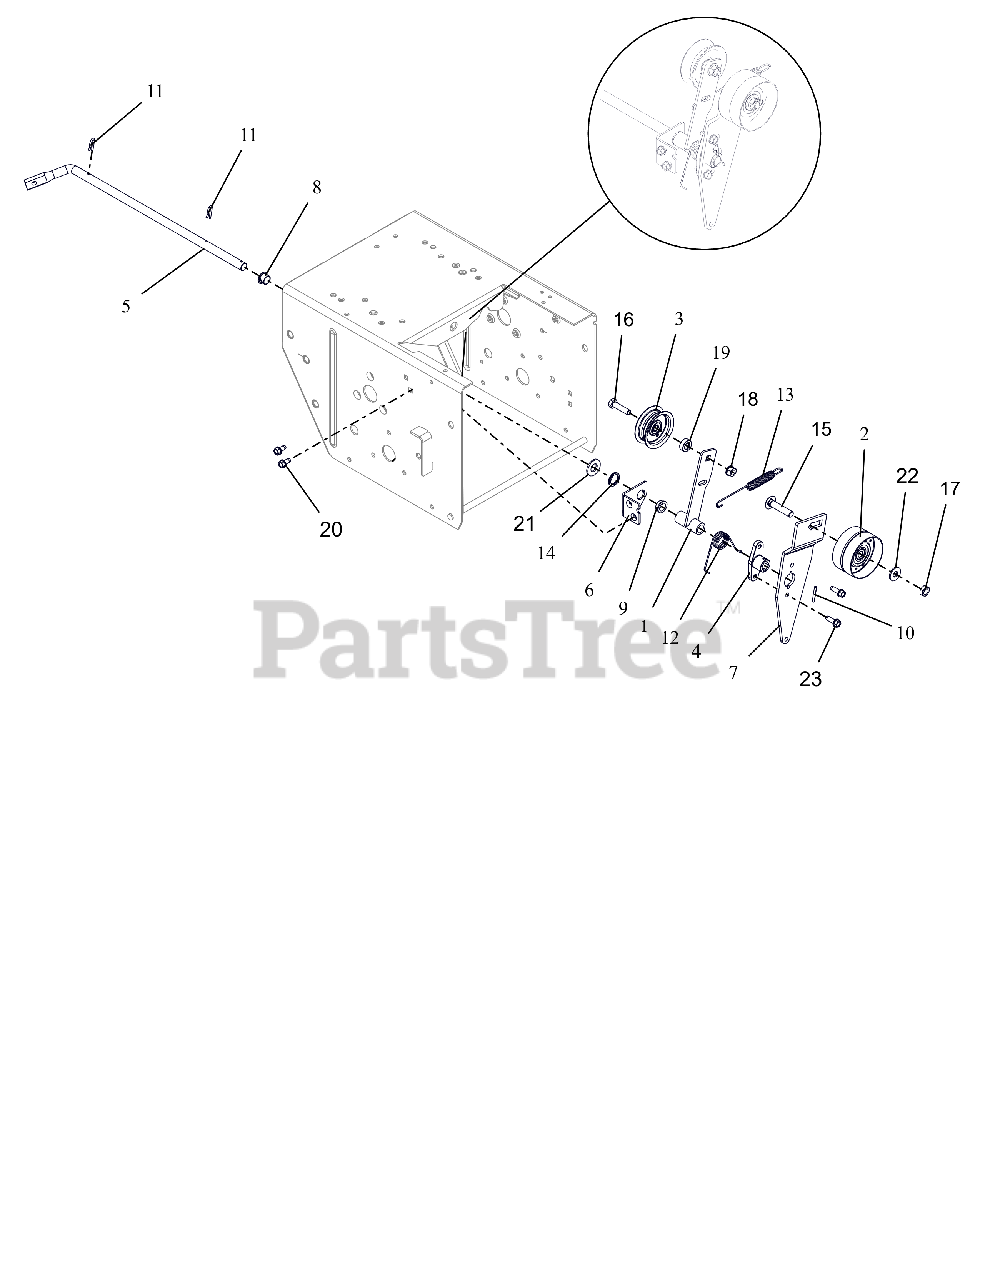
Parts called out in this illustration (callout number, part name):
1	ARM, IDLER-TRACTION
2	IDLER, FLAT-2.75 OD X .375 ID
3	IDLER, FLAT - 2.00"
4	HUB, BRAKE ARM
5	ARM, ATTACHMENT
6	BRACKET, SUPPORT
7	ARM, IDLER-ATTACHMENT
8	BUSHING, POLYLINER-.50 SPLIT
9	BSHG,FLANGE .500X.625X.270X.75
10	PIN-ROLL .125X1.00
11	CLIP, SPRING
12	SG-TORS .067X.88
13	SG-TENS .06X.482X5.35
14	WAVE SPRING .600X.875X.25FH
15	BLT, RHSSN .38-16X1.75 G5 ZCC
16	BLT, HEX .31-18X1.25 G5 ZCC
17	NUT-LK-CTR-JAM .375-16 GB ZCC
18	NUT-LK-TOP-FLG .312-18 GF ZCC
19	SPCR, BRG .315X.500X.358X.281
20	SCR-TAP .25-20X.50 HWH ZCC
21	WSHR,FLT .531X1.062X.095 ZCC
22	WSHR,FLT .375X.875X.083 ZCC
23	SCR,TAP .25-20X.75 HWH TR ZCC
